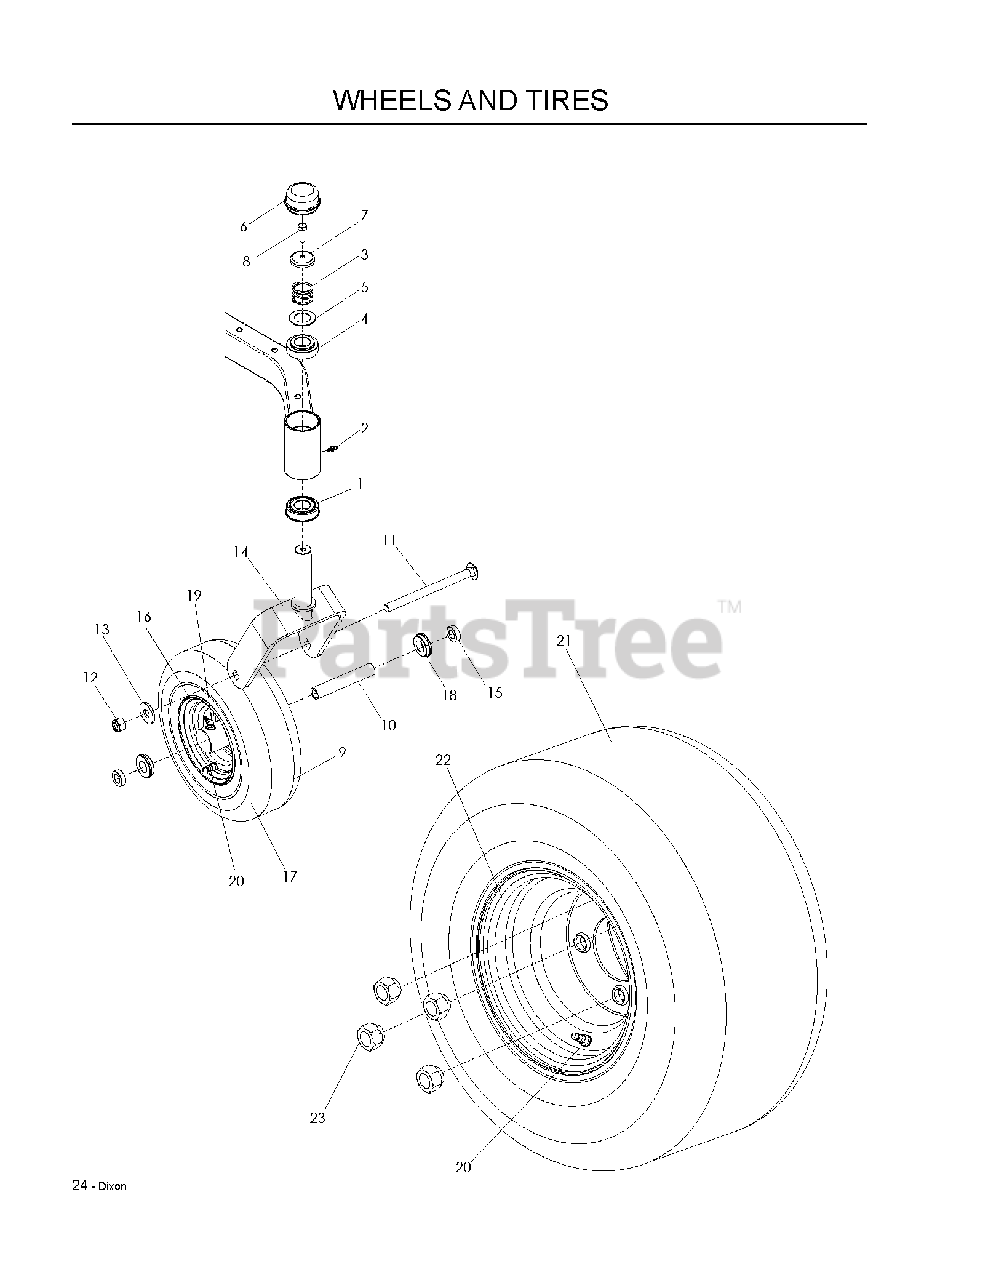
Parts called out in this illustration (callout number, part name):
1	BEARING FLANGED
2	ZERK, 3/16, DRIVE IN
3	SPRING, CASTER
4	BUSHING, CASTER
5	WASHER, 1.025 ID X 1.64
6	GREASE CAP
7	CASTER.PLUG
8	HCS 5/16C X 1
9	TIRE COMPLETE
11	RHSNB 1/2-13 X 6.50 GR2 ZD
12	NUT 1/2-13 HEX NYLOC ZD
13	WASH USS FLAT 1/2
14	CASTER DK BLUE
15	SPACER, 5/16"
17	TIRE - 410/350-5
18	BEARING RETAINER
19	ZERK
20	VALVE STEM TR-412
21	TIRE ASM 18 X 8.5-8
21	TIRE, 18 X 8.5, TURF RIDER
21	TIRE, 20 X 10-8
22	RIM, 8 X 7
23	LUG NUT 1/2F
